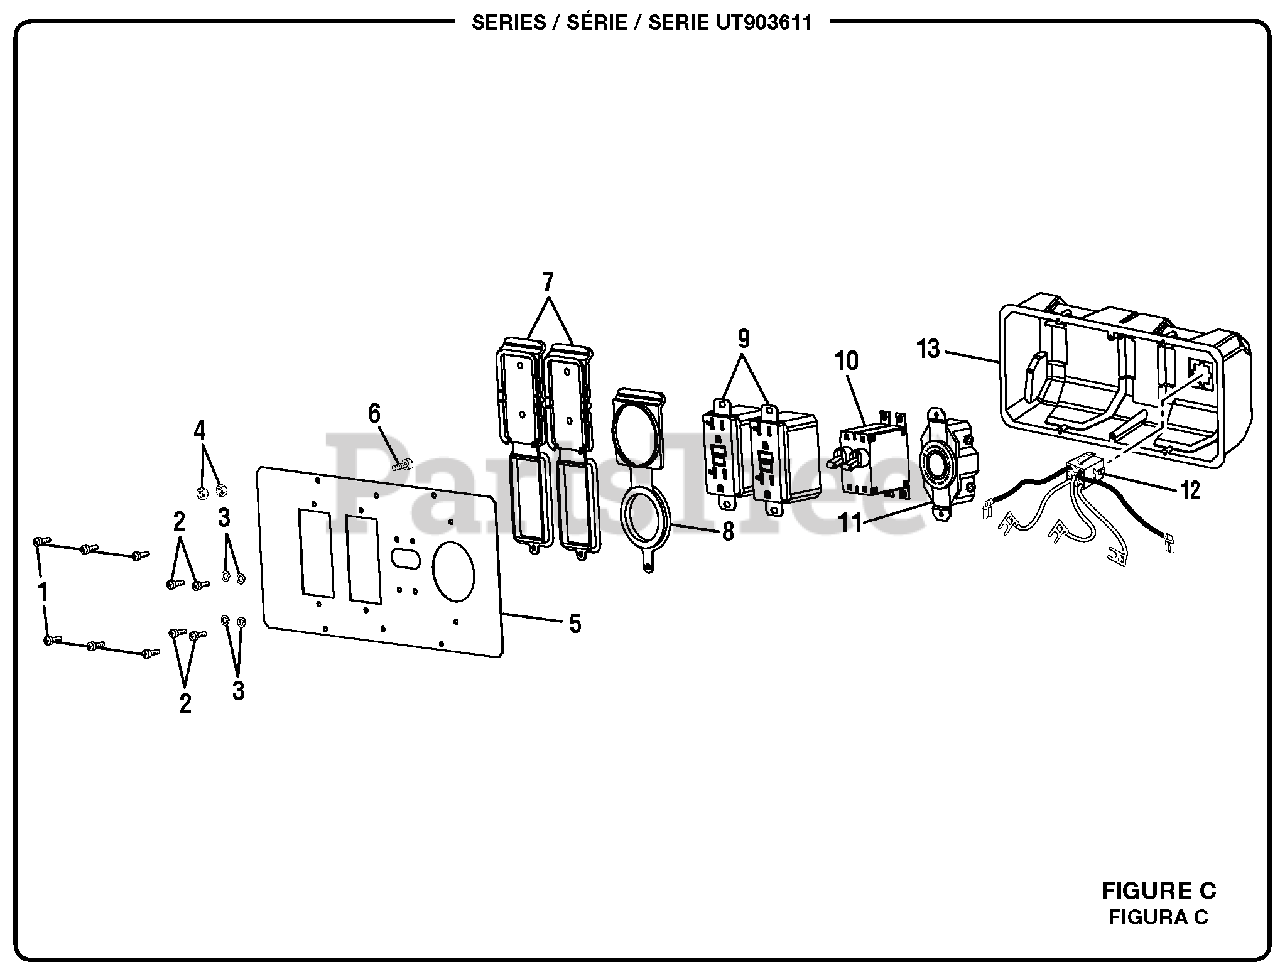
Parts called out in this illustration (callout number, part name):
1	Screw (6-20 x 3/8 in.)
2	Screw (M3 x 6)
3	Lock Washer
4	Hex Nut (1/4-20)
5	Cover Plate
6	Screw (1/4-20 x 5/8 in., Hex Hd.)
7	Outlet Cover (120 Volt)
8	Outlet Cover (240 Volt)
9	Duplex Receptacle (120 Volt)
10	Circuit Breaker (15 Amp, 125 Volt)
11	Twist Lock Receptacle (120/240 Volt, 20 Amp)
12	Connector w/Leads
13	Rear Control Panel
